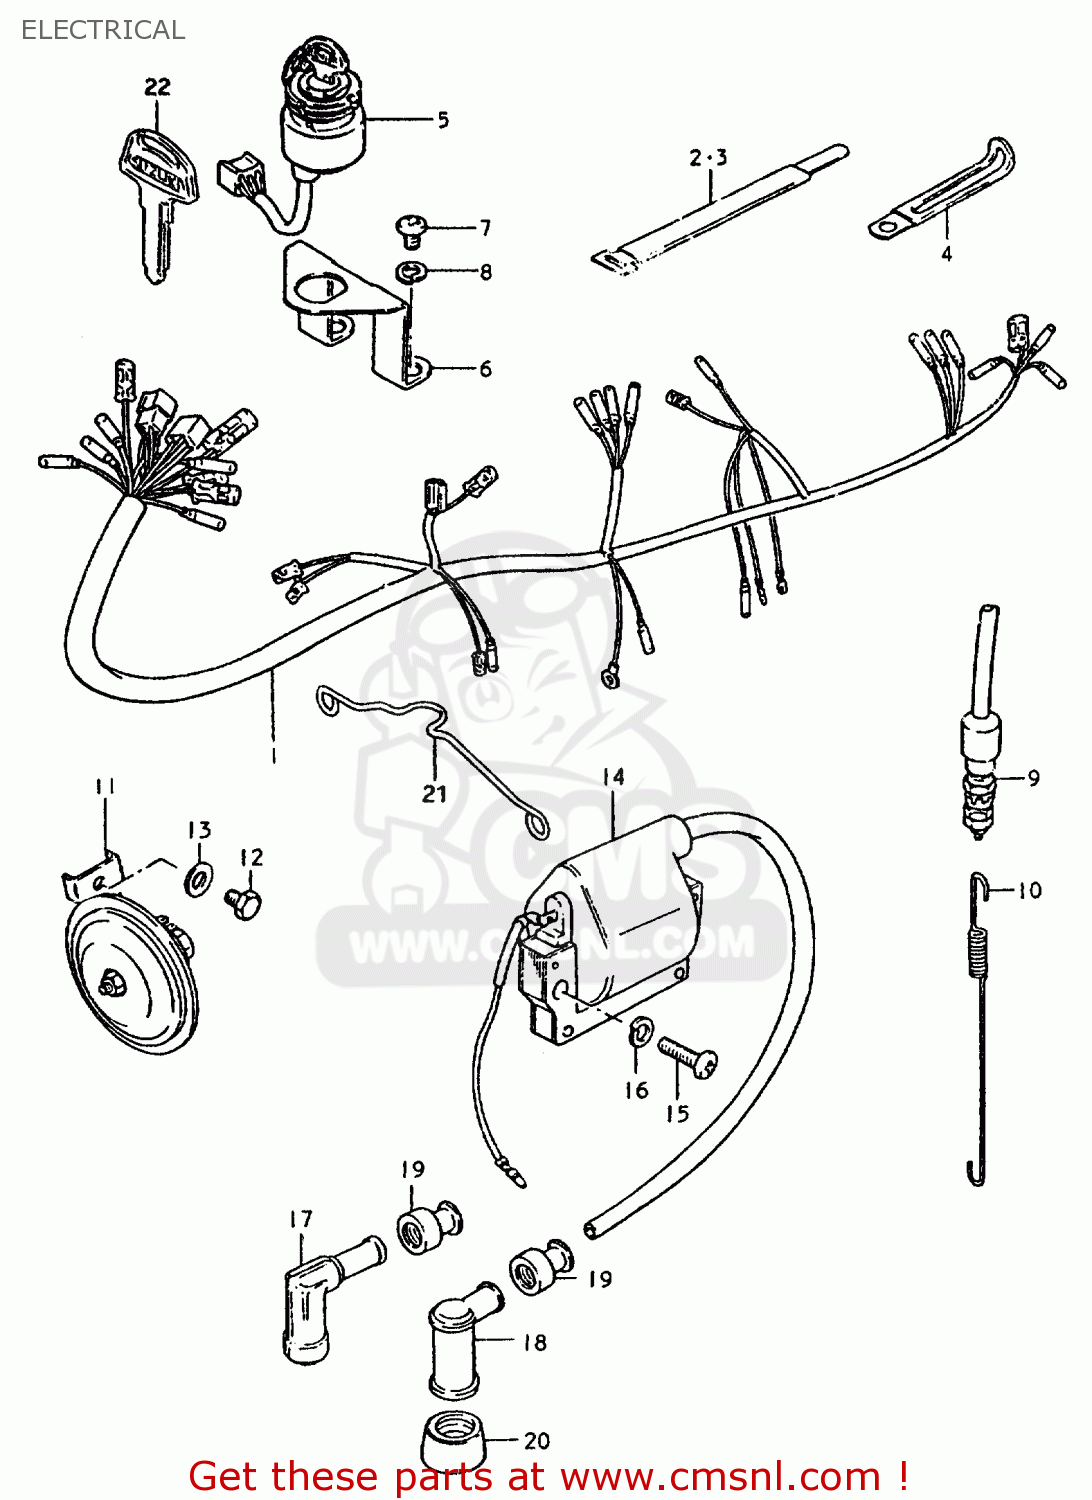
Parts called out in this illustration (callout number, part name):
1	WIRING HARNESS
2	CLAMP
3	CLAMP
4	CLAMP
5	SWITCH ASSY, IGNITION
6	BRACKET,IGNITION SWITCH
7	SCREW
8	LOCK WASHER
9	SWITCH ASSEMBLY,STOP LAMP
10	SPRING
11	HORN
12	BOLT
13	WASHER 6MM
14	COIL ASSEMBLY,IGNITION
15	SCREW
16	LOCK WASHER
17	CAP,SPARK PLUG
18	CAP ASSY,SPARK PLUG
19	SEAL,SPARK PLU
20	SEAL,SPARK PLUG
21	CLAMP
22	KEY,BLANK
